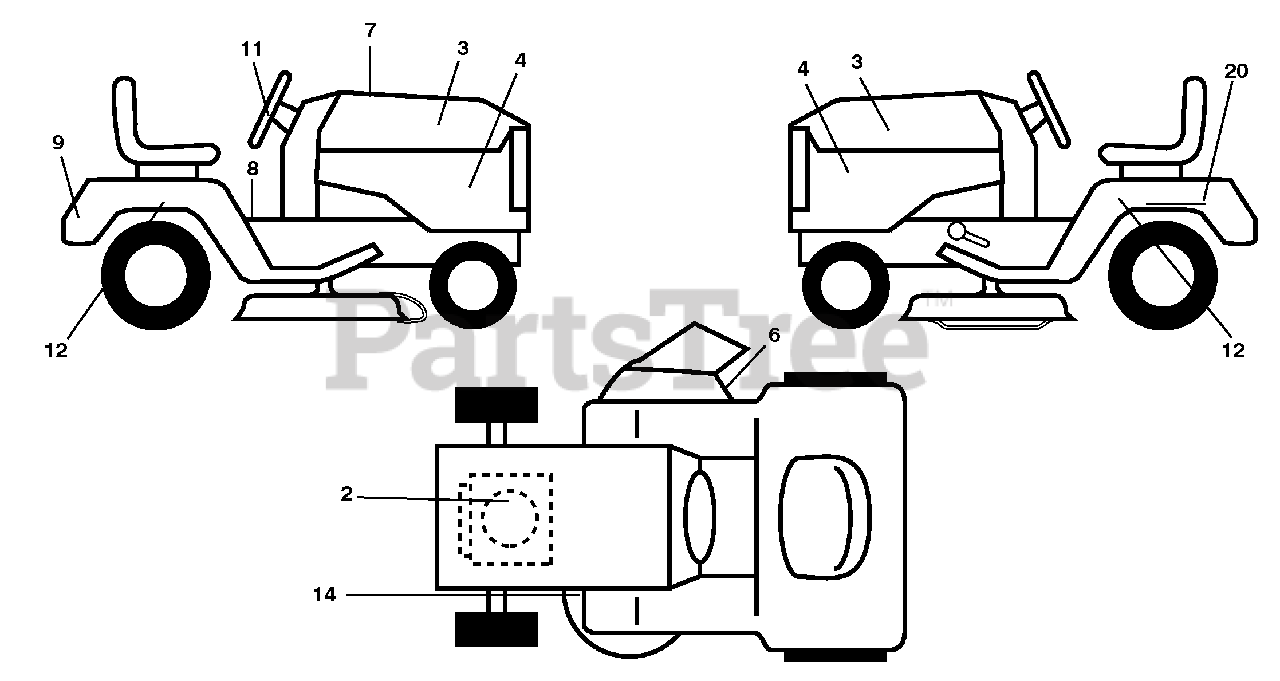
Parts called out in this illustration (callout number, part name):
2	Decal Eng. H.P.
4	Decal Side Panel Logo
6	Decal Warning, Keep Hand Away
7	Decal Replacement Parts
8	Decal Fender Warn S/F
9	Decal Fender Logo
11	Decal Ins Strg Whl
12	Decal Fend SD
14	Decal V-Belt Schematic
20	Decal Bat Dan/Psn
20	Decal Bypass
20	Pad Footrest LH
20	Pad Footrest RH
20	Manual Operator's (English/French)
20	Manual Operator's (Spanish)
20	Manual Parts (English/French)
